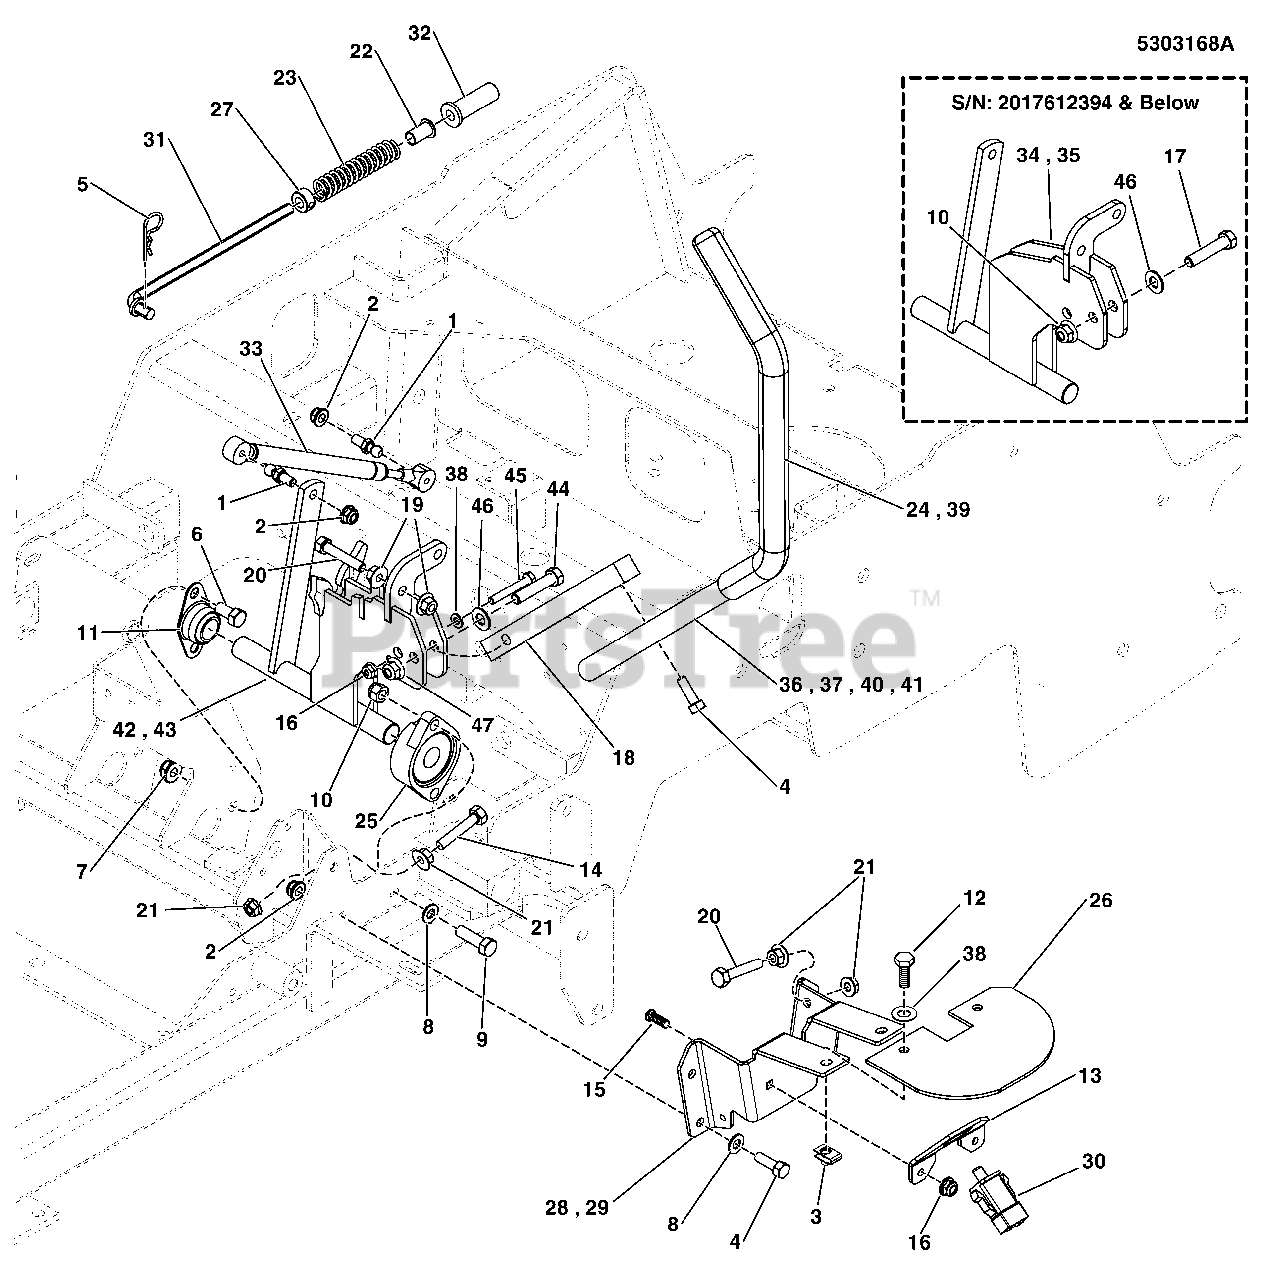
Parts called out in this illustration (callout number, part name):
1	10MM BALL STUD, 5/16-18 X 3/4 THDS
2	NUT, 5/16-18 HEX NYLOCK FLANGE NUT
3	BODY CLIP, 1/4-20 X 1/2" DEEP
4	SCREW, 5/16-18x0.750, GR5, WHIZ-LOCK, ZC
5	3/32 X 1-5/8 HAIR PIN CLIP
6	BOLT, 3/8-16 X 3/4" GD5 CZ
7	NUT, 3/8 - 16 HEX NYLOCK FLANGE
8	WASHER, 5/16" SAE
9	BOLT, Allen Head, 3/8-16 x 1-1/4
10	NUT, 3/8-16 HEX NYLON LOCK
11	BEARING, BRONZE FLANGE, 3/4"
12	BOLT, 1/4"-20 X 3/4" GD5 YZ
13	BRACKET, SWITCH MOUNT - BLK
14	BOLT, 5/16-18 X 1-1/4 GD5 TFL, CZ
15	BOLT,1/4-20X.75,GR5,RH SH SQ NK,ZNC/CLR
16	NUT, 1/4-20 Hex Nylock Flange
17	BOLT, 3/8-16 X 1-3/4" GD5 CZ
18	MOUNT, CONTROL ARM - BLK
19	NUT, 5/16-18 HEX SERRATED FLANGE (LARGE)
20	BOLT, 5/16-18 X 1-3/4 TFL, GD5 YZ
21	NUT, 5/16-18 HEX SERRATED FLANGE (SMALL)
22	BUSHING, FLANGE 3/8ID X 7/8 LONG
23	SPRING, REVERSE RETURN
24	GRIP, FOAM, 3/4" ID, 16"" LONG
25	BEARING, FLANGE
26	PLATE, NEUTRAL LOCK SHIELD - IS700 - BLK
27	COLLAR, 3/8" Set
28	PLATE, NEUTRAL LOCK, LH - BLK
30	SEE ELECTRICAL GROUP
31	ROD, NEUTRAL RETURN, CZ
32	FLANGED BUSHING, 3/8IDX.63ODX.8125FL
33	DAMPENER, CONTROL,#(P6709/P3610)
35	WELD, CONTROL SHAFT, LH - BLK
37	WELD, HANDLE MOTION CONTROL LH - BLK
38	WASHER, 1/4 SAE
39	GRIP, FOAM, 1" ID, 16" LONG
40	WELD, HANDLE MOTION CNTRL, 19.0, 1.0, LH - BLK
42	WELD, CONTROL SHAFT, LOCKOUT, LH - BLK
44	BOLT, 3/8-16 X 1-3/4" GD5 CZ
45	BOLT, 1/4 X 20 X 1-3/4 GD5 YZ
46	WASHER, 3/8 SAE
47	NUT, 3/8 - 16 HEX NYLOCK FLANGE
